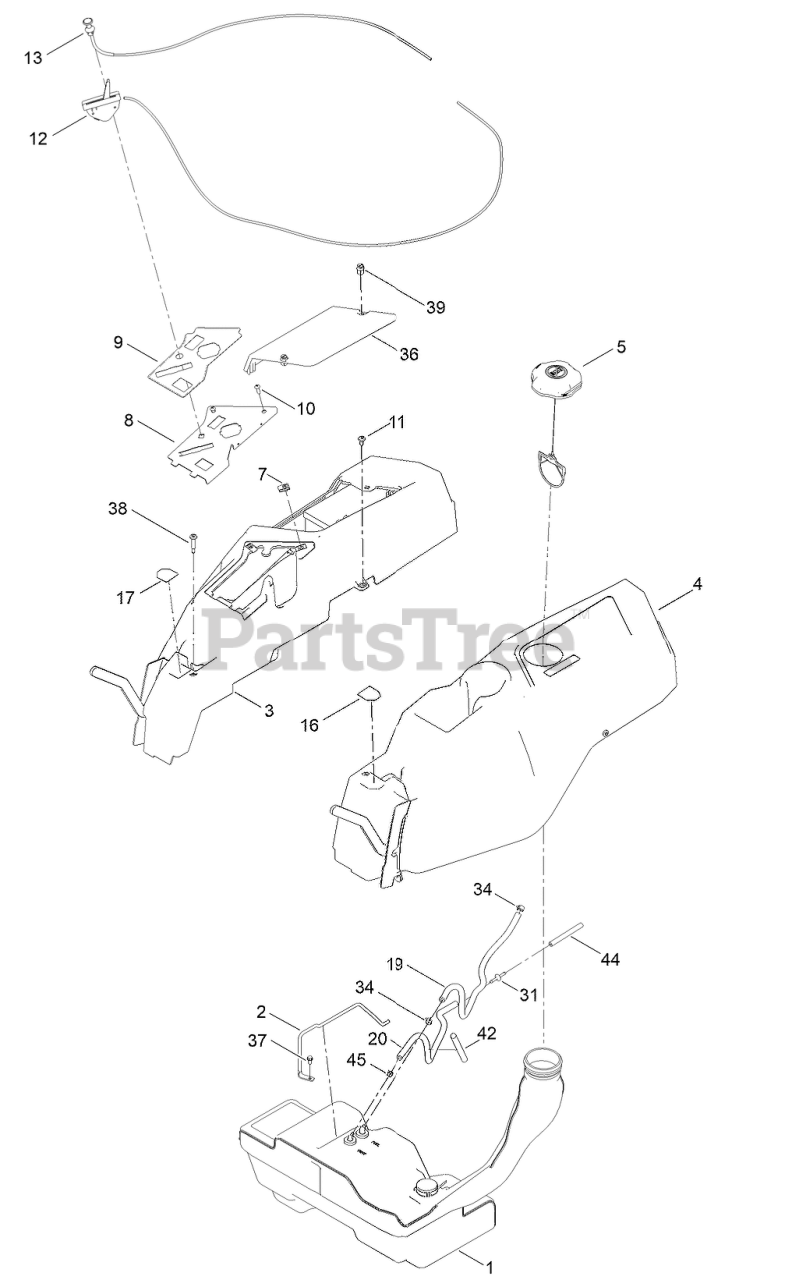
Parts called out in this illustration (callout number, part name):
1	TANK-FUEL ASM
2	ROD-HOLD DOWN
3	POD-RH
4	POD-LH
5	CAP-FUEL, RATCHETING
8	PANEL-CONTROL
9	DECAL-PANEL, CONTROL
10	SCREW-PRH
11	SCREW-SHOULDER
12	CABLE-THROTTLE
13	CABLE-CHOKE
16	DECAL-LEVER, CONTROL (LH)
17	DECAL-LEVER, CONTROL (RH)
19	HOSE-FUEL
20	HOSE-VENT
31	ADAPTER ORIFICE
34	CLAMP-HOSE
36	COVER-BATTERY
37	SCREW-HWH
38	SCREW-SHOULDER
39	FASTENER
42	SLEEVE-FUEL LINE PROTECTOR
44	HOSE-FUEL
45	CLAMP-HOSE
